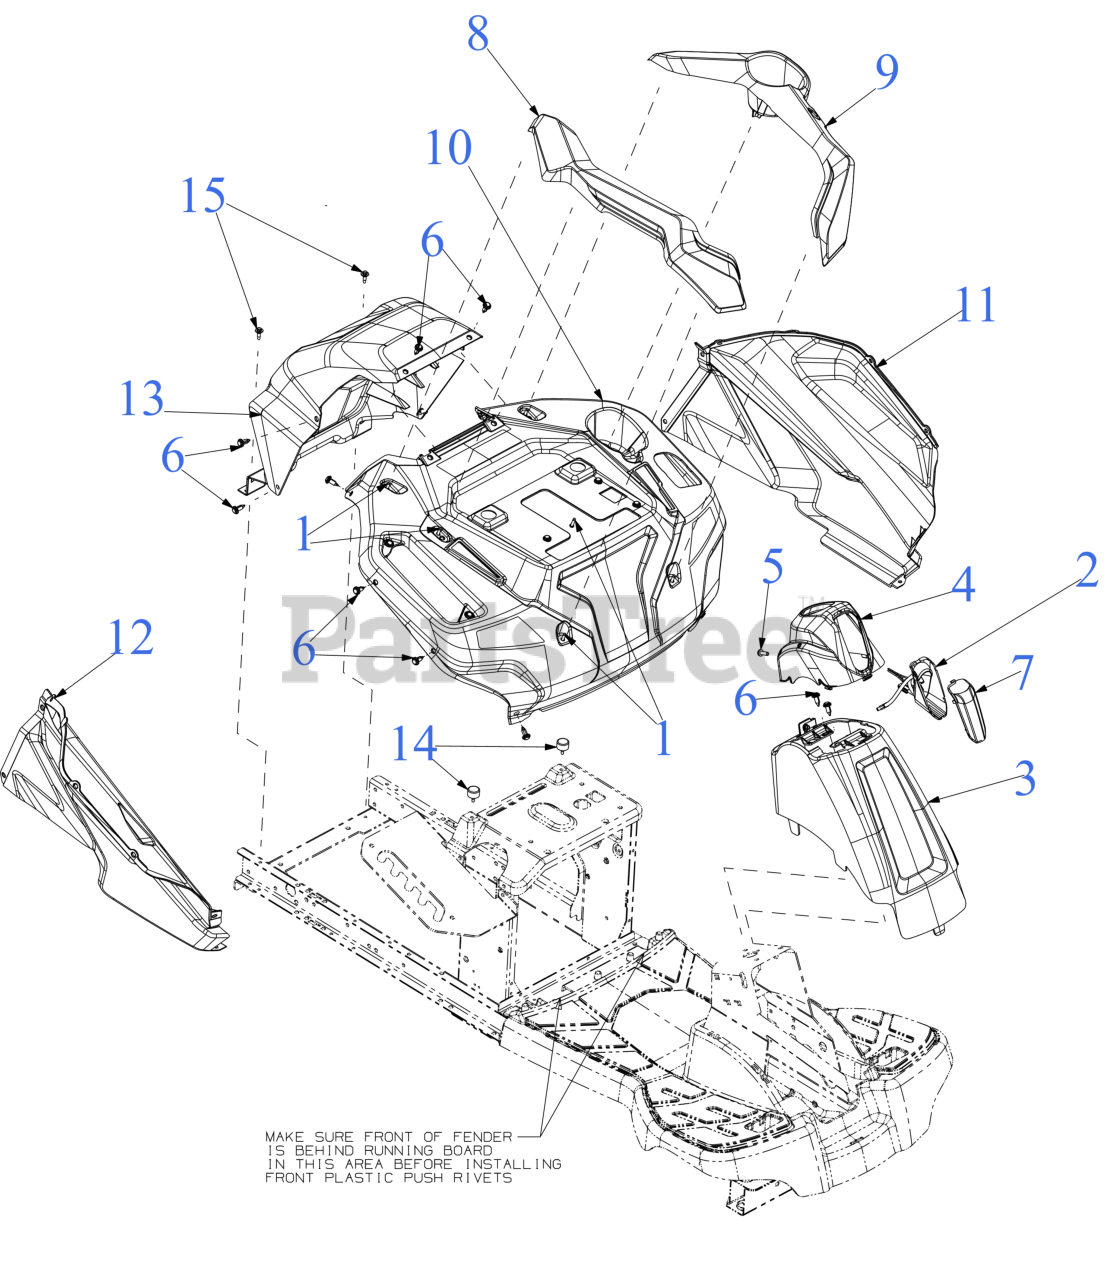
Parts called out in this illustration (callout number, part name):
1	SCREW, #8-16X.750 PH
2	LED HEADLIGHT HARNESS ASSEMBLY
3	COLUMN COVER ASSEMBLY
4	COLUMN CAP (CUB YELLOW)
5	SCREW 1/4-20X.75
6	PLASTIC RIVET
7	LED HEADLIGHT LENS
8	FENDER TRIM (RH) (CUB YELLOW)
9	FENDER TRIM (LH) (CUB YELLOW)
11	BODY PANEL (LH)
12	BODY PANEL (RH)
14	BUMPER .62 DIA x .50
15	SHOULDER SCREW M6-1 .368 X.115
